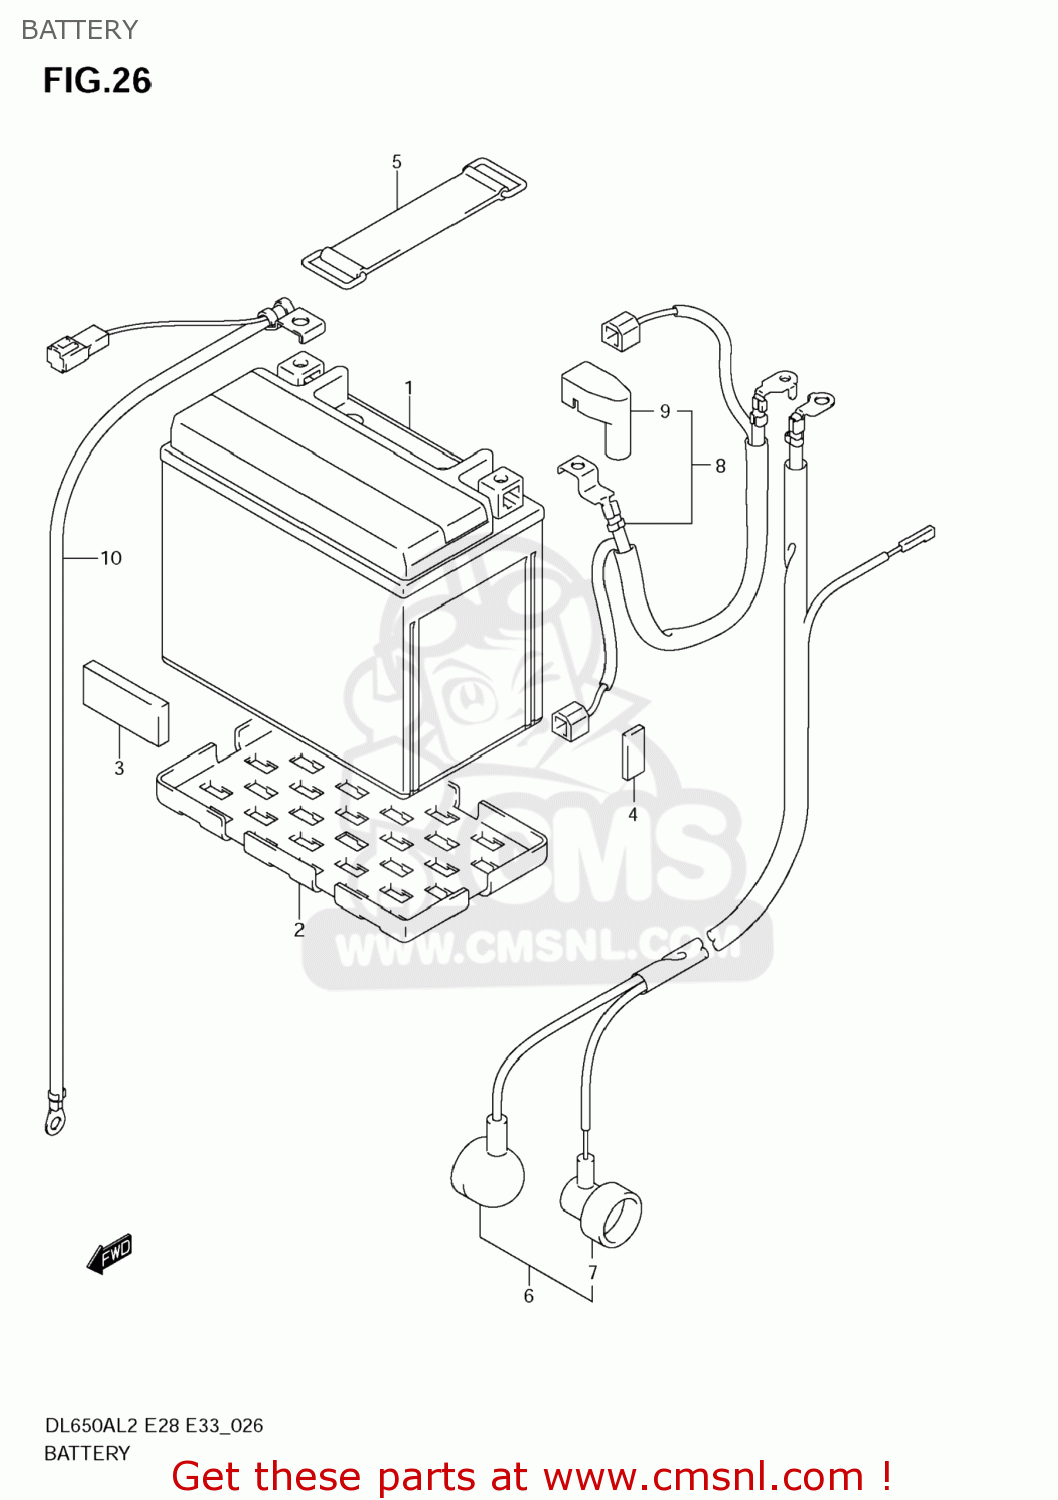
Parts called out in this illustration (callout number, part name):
1	BATTERY(FTX12-BS,12V10.5AH)
2	PROTECTOR,BATTERY
3	PROTECTOR,BATTERY(70X100X6)
4	CUSHION,FUEL TANK NO.2
5	BAND
6	WIRE,STARTER MOTOR LEAD
7	CAP,OIL PRESSURE SWITCH
8	WIRE,BATTERY PLUS LEAD
9	CAP,BATTERY PLUS LEAD
10	WIRE,BATTERY MINUS LEAD
